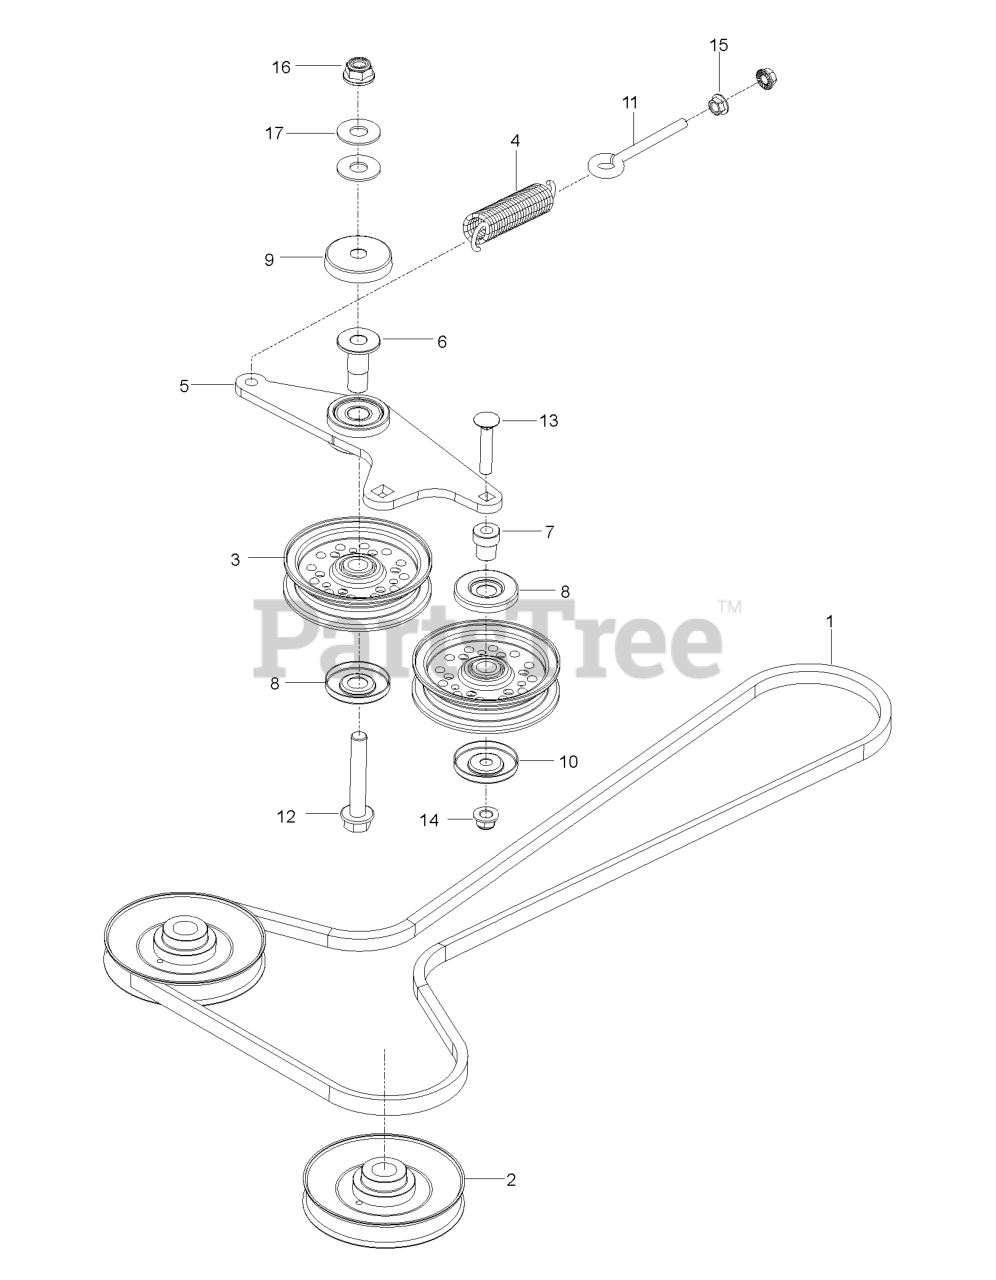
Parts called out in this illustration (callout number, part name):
1	V-BELT GROUND DRIVE 79.52" STA
2	PULLEY PUMP, 5 INCH
3	IDLER PULLEY
4	SPRING, PUMP
5	ARM, IDLER W/BEARING
6	BUSHING, PIVOT
7	PIVOT, IDLER
8	SHIELD, DUST
9	SHIELD, DUST
10	DUST SHIELD
11	EYE BOLT 5/16 X 3.50
12	HFFS 1/2-13 X 3 GD 5 ZD
13	RHSNB 3/8C X 2
14	NUT 3/8-16 HEX FLG NYLOC ZD
15	NUT 5/16C WHIZ
16	NUT, 1/2-13 HEX FLG NYLOC ZD
17	WASHER 1/2 FLAT
